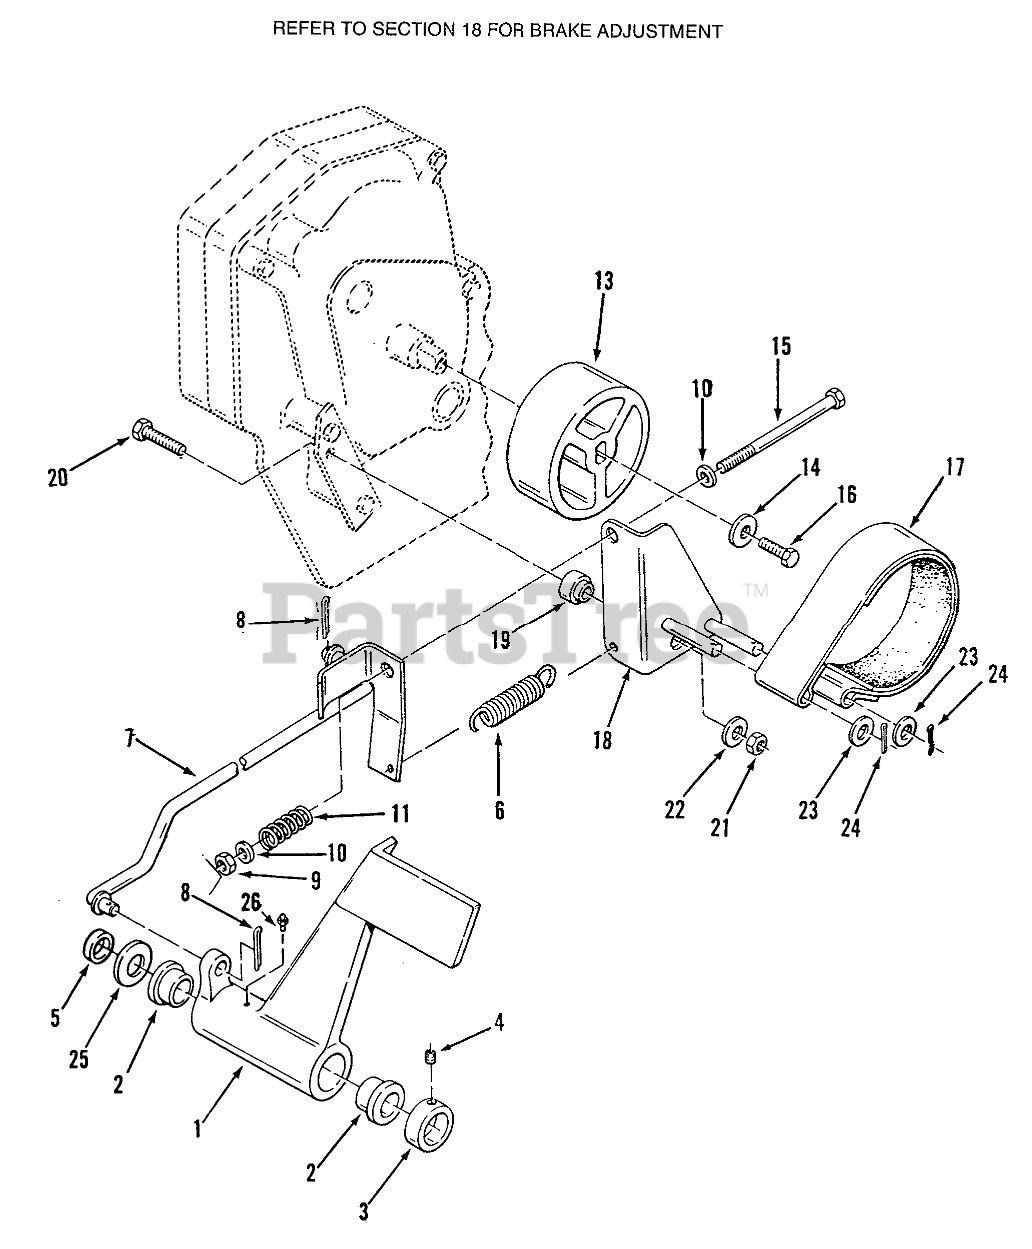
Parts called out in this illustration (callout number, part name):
1	Brake/Return To Neutral Pedal
2	BUSHING
3	Collar
3	Detent-Motion Control Lever
4	SCREW-SET
4	H H C S
5	Hose ASM-Hydraulic
5	Nut
6	SPRING
7	ASY BRAK RD WAR
9	NUT
10	Washer
11	SPRING-COMPRESSION
13	DRUM-BRAKE
14	WASHER
15	BOLT
16	BOLT
17	ASSY-BRAKE BAND
18	Brake Pivot Arm
19	BUSHING-BRAKE PIVOT
20	BOLT
21	Nut
22	Washer
23	Washer
24	Cotter Pin
25	WASHER
26	Zerk
